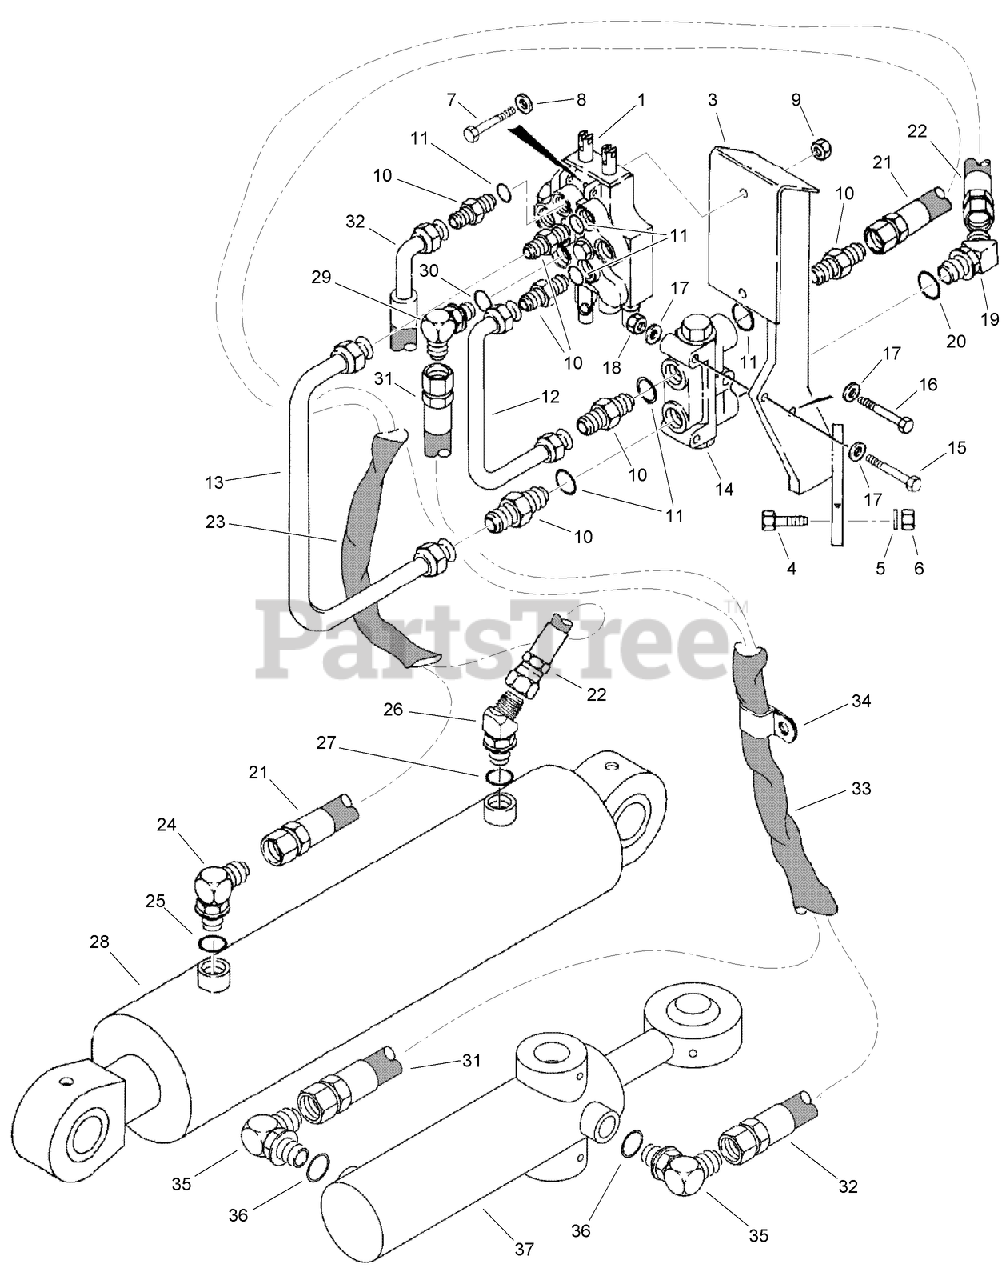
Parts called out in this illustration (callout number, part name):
1	VALVE ASSEMBLY - Control, Plow Lift and Swing
3	BRACKET - Mounting, Plow Control Valve
4	SCREW-HH
6	NUT-HEX
7	BOLT - Hex, 5/16 NC x 2-3/4 inch
8	WASHER-FLAT
9	NUT-HEX
10	CONNECTOR
11	O-RING
12	TUBE - to Lockout Valve -A- Port
13	TUBE - to Lockout Valve -B- Port
14	HYD LOCKOUT VALVE ASM
15	BOLT - Hex, 5/16 NC x 2-3/4 inch
16	BOLT - Hex, 5/16 NC x 3 inch
17	WASHER-FLAT
18	NUT-HEX
19	ELBOW-8MO x 6MJ 45 Deg Adapter
20	O-RING
21	HOSE - 685 mm (27 inch) Long, Lockout Valve -C- Port to Plow Lift Cylinder, Rod End
22	HOSE - 450 mm (17-3/4 inch) Long, Lockout Valve -D- Port to Plow Lift Cylinder, Closed End
23	SLEEVE - Nylon, 32 (1-1/4) ID x 250 mm (9-7/8 inch) Long, Lift Cylinder Hoses
24	ELBOW-90 DEG (ADJUSTABLE 37 DEG)
26	ELBOW-45 Adj 37FL 3/8 Tube
28	CYLINDER ASSEMBLY - 89 (3-1/2) ID x 290 mm (11-13/32 inch) Stroke, Plow Lift
29	ELBOW-90 Adj 37FL, 3/8 x 1/2 Tube
30	O-RING
31	HOSE - 510 mm (20 inch) Long, Plow Control Valve to Plow Swing Cylinder, Closed End
32	HOSE-Hydraulic
33	SLEEVE - Nylon, 32 (1-1/4) ID x 250 mm (9-7/8 inch) Long, Lift Cylinder Hoses
34	CLAMP - P-Type, 5/8 inch Diameter, Hose
35	ELBOW-90 DEG (ADJUSTABLE 37 DEG)
37	CYLINDER ASSEMBLY - 51 (2) ID x 143 mm (5-5/8 inch) Stroke, Plow Swing
